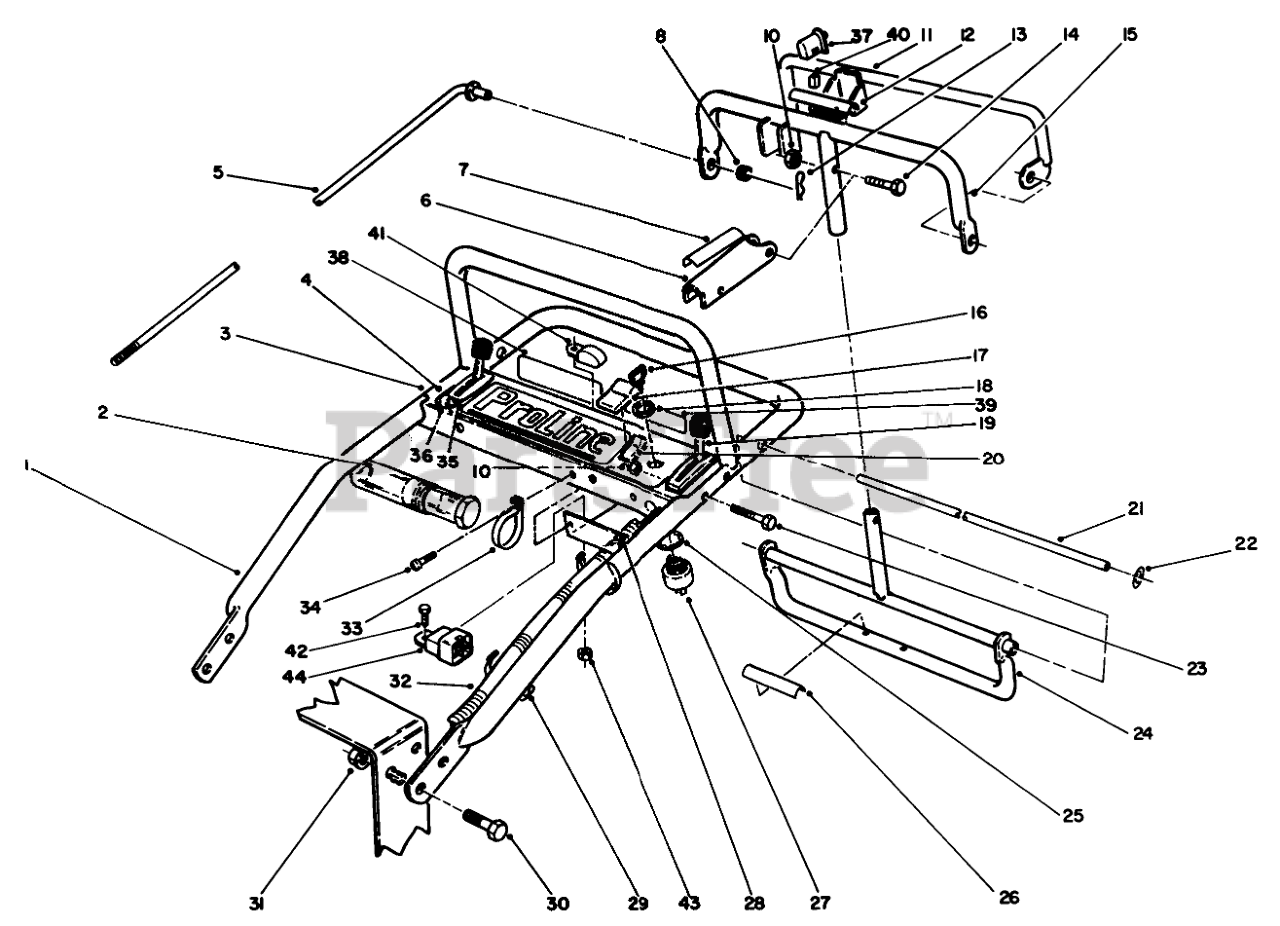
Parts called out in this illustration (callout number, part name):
1	Handle-Upper
2	TUBE-MANUAL
3	Panel-Control
4	DECAL-CNTRL PANEL-30175
5	ROD-CONTROL
6	Lever-Parking Brake
7	DECAL-LEVER, PARKING
8	GROMMET-RUBBER
10	NUT-LOCK, NI
11	Bail
12	DECAL
13	PIN-COTTER
14	SCREW-SHH
15	Bar
16	KEY-IGNITION
17	BOOT-SWITCH
18	NUT-HH
19	THROTTLE CONTROL
20	Switch-Clutch (Incl. Ref. #17)
21	PIVOT ROD
22	NUT-PUSH-ON, CIRCULAR
23	SCREW-SHH
24	Control Pivot
25	WASHER-TOOTH, INTERNAL
26	DECAL
27	Switch-Ignition (Incl. Ref. #16,18, & 25)
28	Panel-Bottom
29	TIE-CABLE
30	SCREW-HHF
31	NUT-HF
32	WIRE HARNESS
33	CLAMP-R
34	SCREW-HWHTF
35	CHOKE CONTROL
36	SPACER
37	SWITCH-BAIL
38	DECAL-INSTRUCTION, SAFETY
39	DECAL-INSTRUCTION
40	CONNECTOR-BODY
41	Module
42	SCREW-HH
43	NUT-LOCK, NI
44	RELAY
